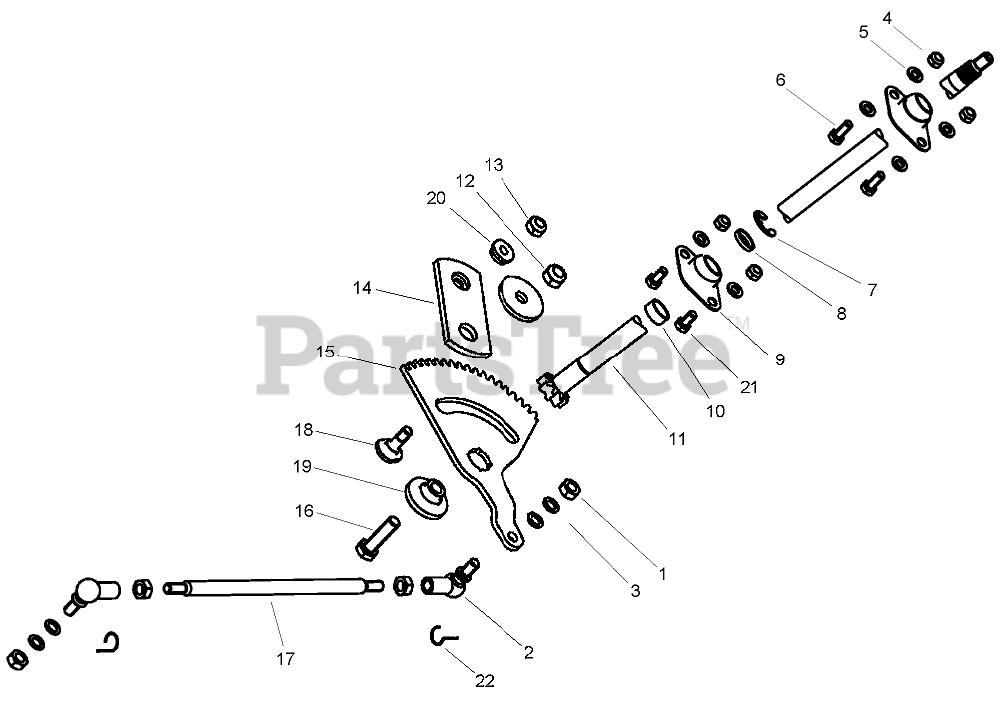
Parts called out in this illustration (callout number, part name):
1	NUT-HEX
2	JOINT-BALL, ANGLE
3	Washer
4	NUT-LOCK, NI
5	WASHER-PLAIN
6	SCREW-HH
7	CLIP-SPRING
8	SPACER-UPPER
9	BEARING-SPHERICAL
10	SPACER-LOWER
11	Shaft-Steering
12	NUT-LOCK
13	NUT-LOCK, NI
14	Plate-Steering
15	GEAR-SECTOR
16	SCREW-HH
17	LINK-DRAG
18	Bolt-Shoulder
19	Pivot-Steering
20	Bushing
21	SCREW-HH
22	Stirrups-Locking
